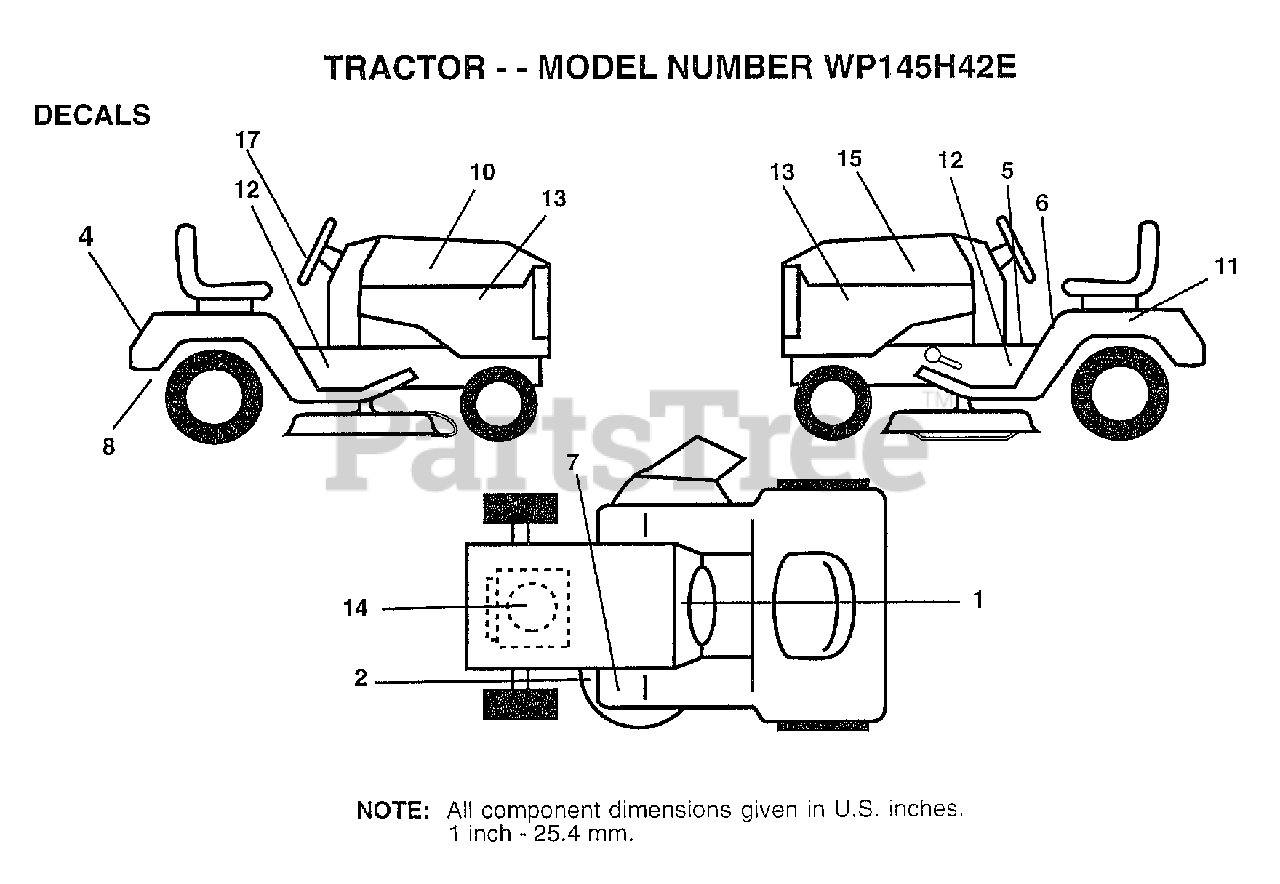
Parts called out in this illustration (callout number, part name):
1	"DECAL-INST,OPER"
2	"DECAL-SCHEM,BELT"
4	DECAL, FENDER LOGO
5	DECAL BRAK PARK
6	"DECAL DANGER,FEND"
8	DECAL DRAWBAR LH
10	DECAL.HOOD.RH
11	DECAL.BATRY.3-3908
12	DECAL CHAS 42 HYD
13	DECAL.WP145H42A
14	DECAL, ENGINE
15	DECAL.HOOD.LH
17	DECAL, INSERT
